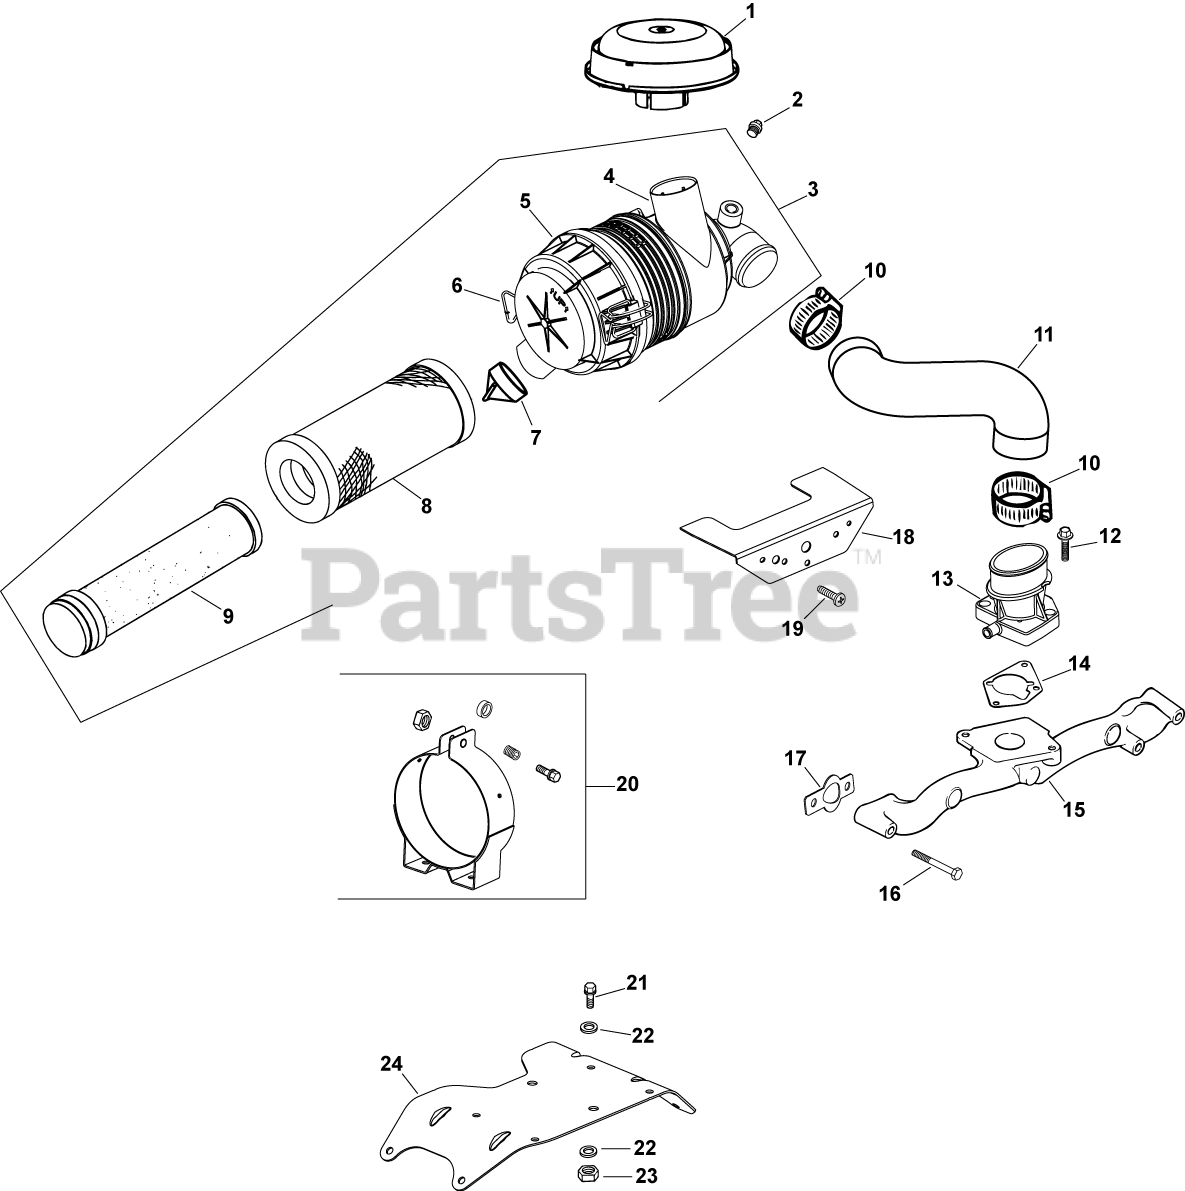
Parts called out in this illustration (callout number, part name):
1	HOOD, AIR CLEANER (5.25)-USE 25 324 04-S
2	PLUG, PIPE
3	CLEANER, AIR-USE 25 048 17-S
4	HOUSING, HD AIR CLEANER
5	COVER ASSEMBLY, AIR CLEANER
6	CLIP, MOUNTING-USE 25 154 13-S
7	VALVE, DUST EJECTOR
8	ELEMENT, AIR FILTER - PRIMARY
9	ELEMENT, AIR FILTER - SAFETY
10	CLAMP, HOSE
11	HOSE, AIR CLEANER
12	SCREW - USE 25 086 124-S
13	ADAPTER, AIR CLEANER -USE 24 029 82-S
14	GASKET, AIR CLEANER BASE
15	MANIFOLD, METAL INTAKE
16	SCREW, FLG M6X1.0X55
17	GASKET, INTAKE MANIFOLD USE 24 041 79-S
18	SHIELD, DEBRIS
19	SCREW, PHL HD 11-16X3/4"
20	BRACKET, AIR CLEANER-USE 24 126 191-S
21	SCREW, FLG M6X1.0X16
22	WASHER, FLAT 1/4" (O.D. 1")
23	NUT, LOCK M6X1.0
24	BRACKET, AIR CLEANER
